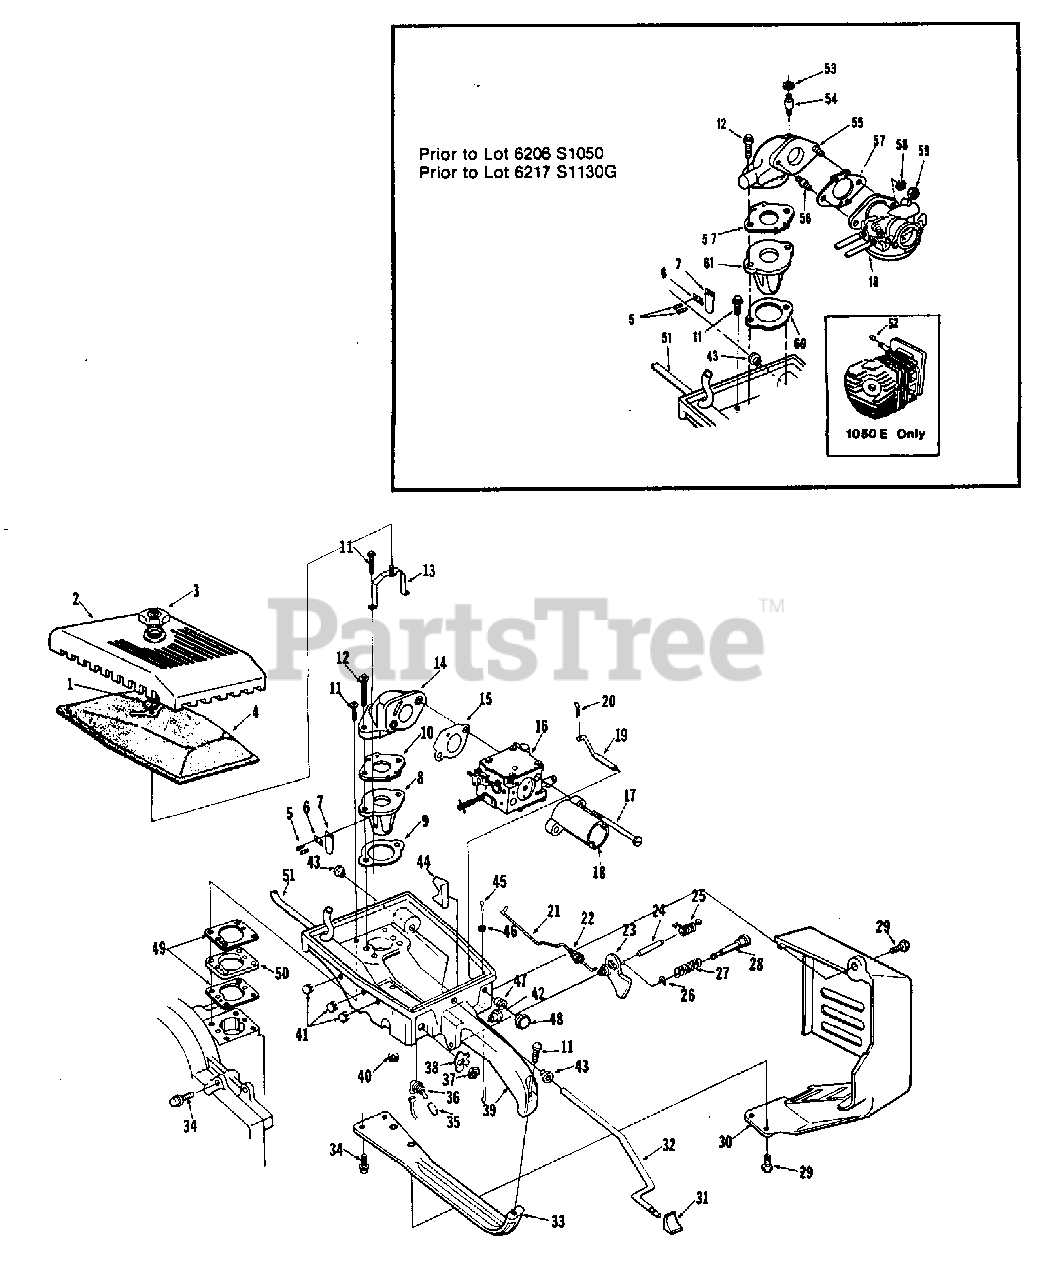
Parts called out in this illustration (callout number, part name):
1	RING- Retaining
2	COVER- Air filter
3	NUT- Cover
4	FILTER ELEMENT- Air
5	SCREW- Pan hd., 4-40 x 3/16
6	CLAMP- Reed
7	REED- Valve
8	SEAT- Reed valve
9	GASKET- Spacer-adapter
10	GASKET- Carburetor
11	SCREW- Hex hd., 12-24 x 1
12	SCREW- Hex hd., 1/4-20 x 1-1/2
13	BRACKET & STUD
14	MANIFOLD- Intake
15	GASKET- Carburetor
16	CARBURETOR (SDC-74)
17	SCREW- Hex mach., 10-32 x 2.25
18	TUBE- Spitback
19	ROD- Choke
20	PIN- Cotter
21	ROD- Throttle
22	BOOT- Throttle rod
23	TRIGGER- Throttle
24	SHAFT- Throttle trigger
25	SPRING- Throttle trigger
26	RING- Retaining
27	SPRING- Throttle latch
28	PIN- Throttle latch
29	SCREW- Hex hd. 12-24 x 5/8
30	SHIELD- Muffler
31	BUTTON- Oil rod
32	ROD- Oil pump (S1050 AO)
33	BRACE- Throttle handle
34	SCREW- Hex hd., 12-24 x 3/4
35	SLEEVE- Grounding switch
36	SWITCH- Toggle
37	NUT
38	PLATE- ("RUN-STOP")
39	HANDLE- Throttle (carb. chamber)
40	PLUG- Button w/59765 "O" Ring
41	PLUG- Button w/59765 "O" Ring
42	BUSHING- Nylon
43	BUSHING- Nylon
44	STOP- Oil pump rod
45	PIN- Cotter
47	GROMMET
48	BUTTON- Rod
49	GASKET- Spacer
51	TUBING- Rubber (fuel line)
52	PLUG- Cylinder tube (S1050E only)
53	GASKET- Stud
54	STUD- Cover
55	MANIFOLD- Intake
56	STUD- Carburetor
57	GASKET- Carburetor
58	WASHER- Lock 1/4"
59	NUT- Hex, 1/4-20
60	GASKET- Spacer adapter
61	SEAT- Reed valve
